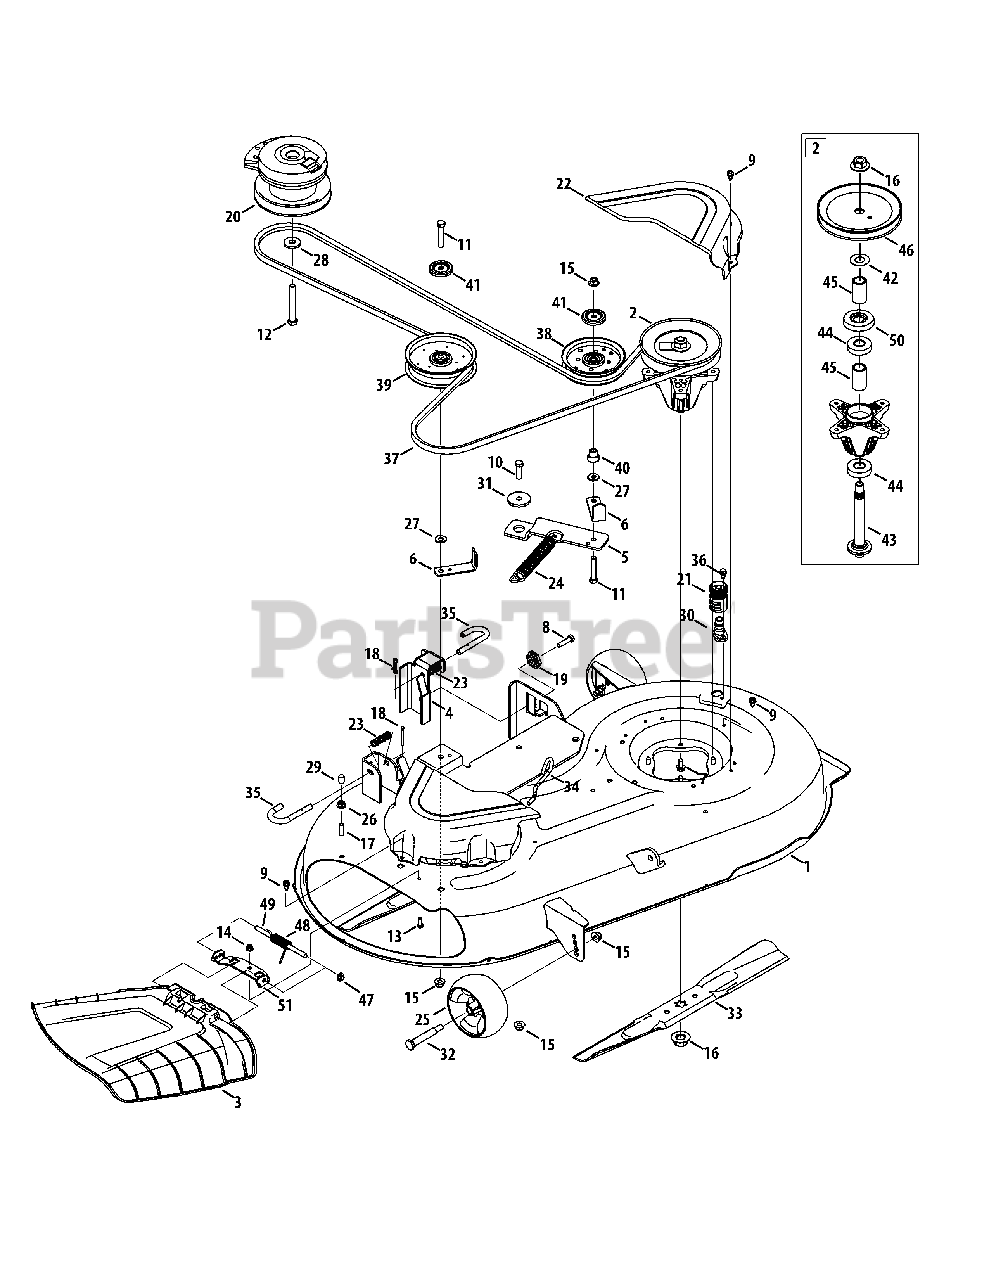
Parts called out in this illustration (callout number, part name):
1	42" Deck
2	Spindle Assembly
3	Chute Deflector Assembly
4	Deck Lift Bracket
5	Pivot Idler Bracket
6	Bracket Belt Guard
7	Hex Washer Screw, 5/16-18 x .750
8	Hex Cap Screw, 3/8-16 x 1.50
9	Hex Washer Screw, 1/4-20 x .625
10	Hex Cap Screw, 3/8-16 x 1.25
11	Hex Cap Screw, 3/8-16 x 2.00
12	Screw, 7/16-20 x 3.25
13	Hex Cap Screw, 1/4-20 x .62
14	Nut, Flange Lock, 1/4-20, Nylon
15	Flange Lock Nut, 3/8-16
16	Hex Flange Nut, 5/8-18
17	Hex Cap Screw, 5/16-18 x 1.00
18	Cotter Pin, 5/32 x 1.25
19	Deck Adjustment Gear
20	Electric PTO Clutch
21	Water Nozzle Adapter
22	Belt Cover
23	Compression Spring, .66 x 1.9
24	Extension Spring, .94 Dia. x 7.57
25	Deck Ball Wheel, 5.0
26	Flange Lock Nut, 5/16-18
27	Flat Washer, .385 x .870 x .092
28	Flat Washer, .450 x 1.25 x .164
29	Cap, .290 x .500
30	Deck Wash Nozzle
31	Shoulder Spacer, .884 x .190
32	Shoulder Screw, .5 x 2.5 x 3/8-16
33	Blade, 2 in 1, 21.23
34	Deck Spring Rod
35	Deck Hanger Rod
36	Shoulder Screw, 1/4-20 x 0.50
38	Idler Pulley, 4.25 Dia.
39	Idler Pulley, 5.00 Dia.
40	Shoulder Spacer
41	Pulley Cap
42	Washer, .760 x 1.50 x .030
43	Spindle Shaft
44	Ball Bearing
45	Spacer, .792 x 1.060 x 1.860
46	Deck Pulley
47	Push Cap
48	Spring, Torsion, .440 ID x 1.75
49	Hinge Pin
50	Bearing Shield
